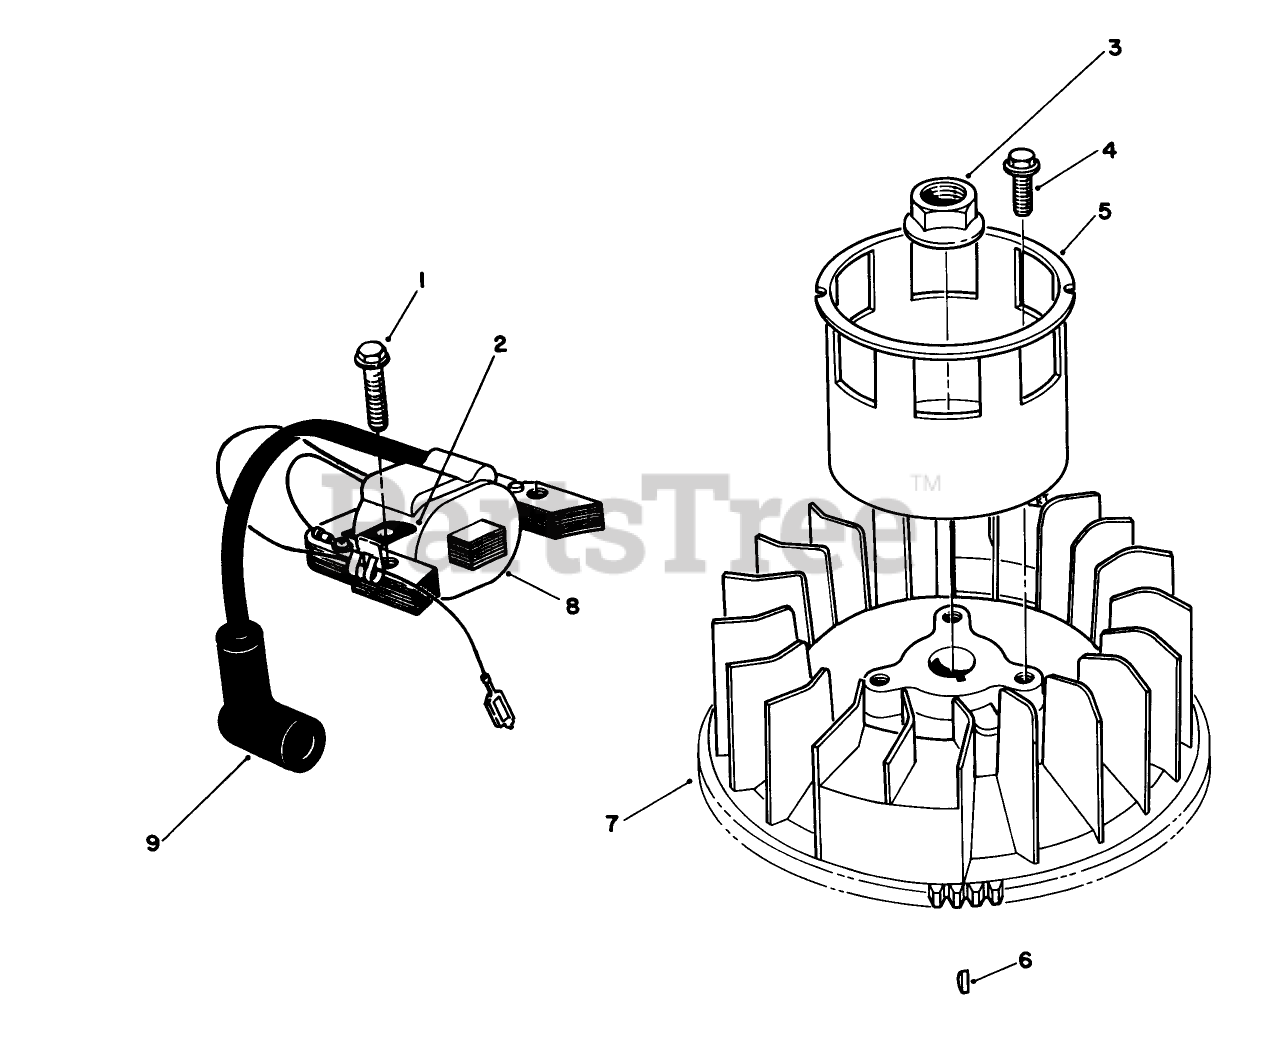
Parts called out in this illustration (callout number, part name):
2	CLAMP
7	FLYWHEEL
8	COIL ASM
9	COVER
